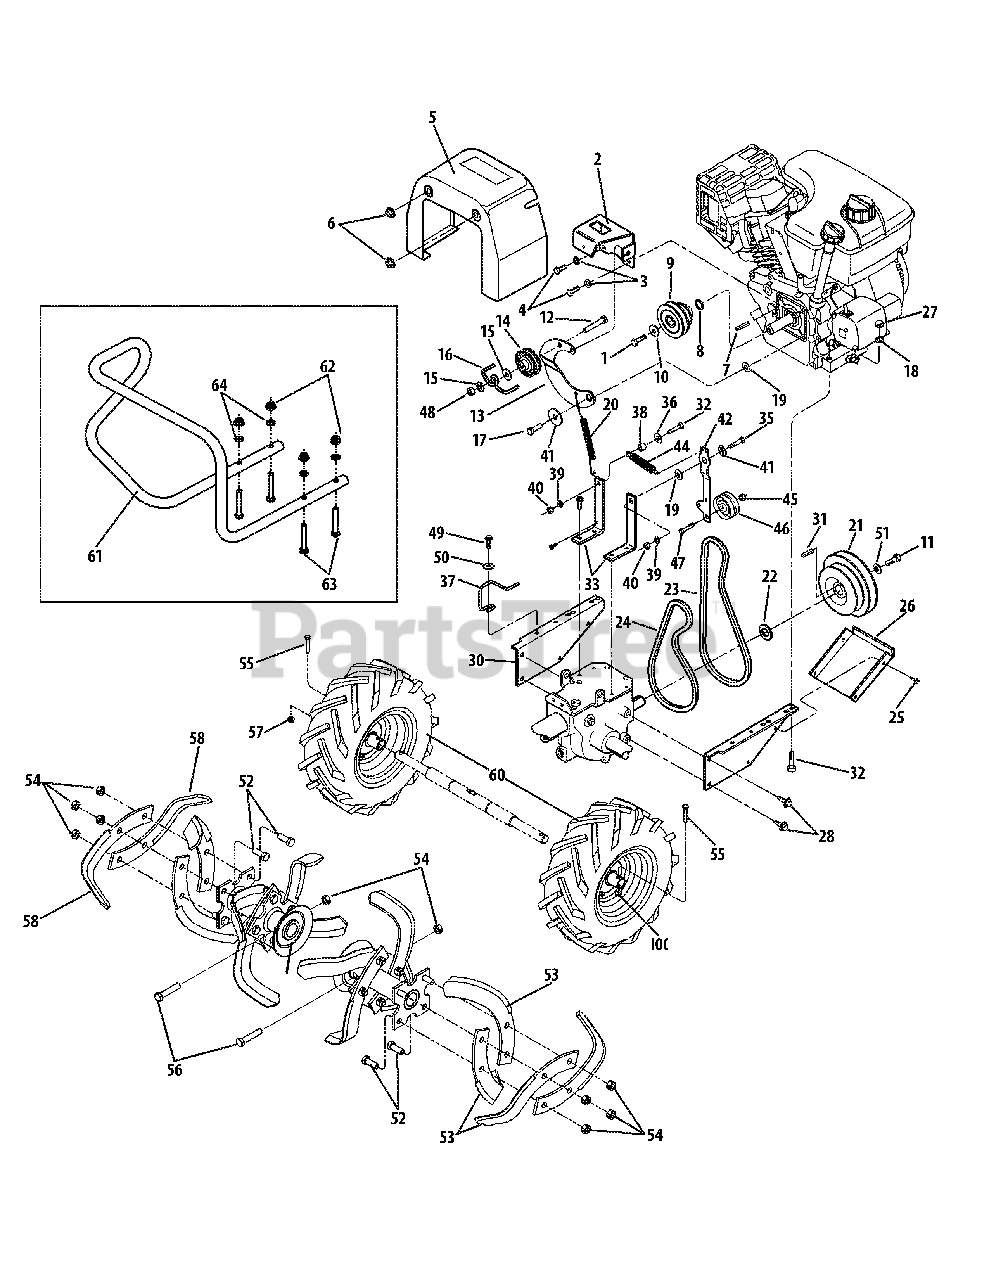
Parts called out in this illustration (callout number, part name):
1	Hex Screw, 3/8 -24 x 2.25
1	Screw, 3/8 -24 x 1.75
1	Screw, 5/16-24 x 1.25
4	Hex Head Screw,5/16-24 x 1/2
6	Flange Lock Nut, 5/16-18
7	Key, 3/16-2
7	Key, 3/16 x 1.75
7	Key, 3/16 x 1.5
9	Engine Pulley
10	Belle. Washer, .344 x 1.0 x .063
10	Belle. Washer .827 x .331 x .098
11	Hex Head Screw, 5/16-24 x 1-1/8
12	Hex Head Screw, 5/16-18 x 2
13	Reverse Idler Arm
14	Reverse Idler Pulley
15	Flat Washer, 5/16
16	Wire Formed Belt Guide
17	Hex Head Screw, 5/16-24 x 1
18	Speed Nut, .3125
19	Flat Washer, 1-1/8
20	Reverse Return Spring
21	Transmission Pulley
22	Support Washer
23	Reverse Clutch Belt
24	Forward Clutch Belt
25	Self-tapping Screw, #10-32 x 1/2
27	Hex Flange Nut, 5/16-18
28	Hex Flange Screw, 5/16-18 x 3/4
31	Key, 3/16 x 1.50
32	Hex Head Screw, 5/16-18 x 2-1/4
33	Mounting Bar
34	Hex Flange Screw, 5/16-18 x .75
35	Hex Head Screw, 5/16-18 x 1-1/2
36	Flat Washer, 5/16
37	Belt Guide
38	Pivot Bushing
39	Lock Washer, 5/16
40	Hex Nut, 5/16-18
41	Shoulder Washer
43	Self-tapping Screw, #10-24
44	Spring
45	Hex Locknut, 5/16-18
46	Forward Idler Pulley
47	Screw, 3/8-16 x 1-3/4
48	Hex Lock Nut, 5/16-18
49	Screw, 1/4-20 x 3/4
50	Flat Washer, 1/4
51	Belleville Washer, .827 x .331 x .098
52	Hex Head Screw, 3/8-16 x 1
54	Hex Locknut, 3/8-16
55	Hex Head Screw, 1/4-20 x 1.5
56	Hex Head Screw, 3/8 -16 x 2
57	Flange Hex Locknut, 1/4-20
60	Wheel Assembly, 13 x 5 x 6
62	Hex Lock Nut, 5/16-18
63	Hex Screw, 5/16-18 x 2-1/4
64	Speed Nut, .3125
